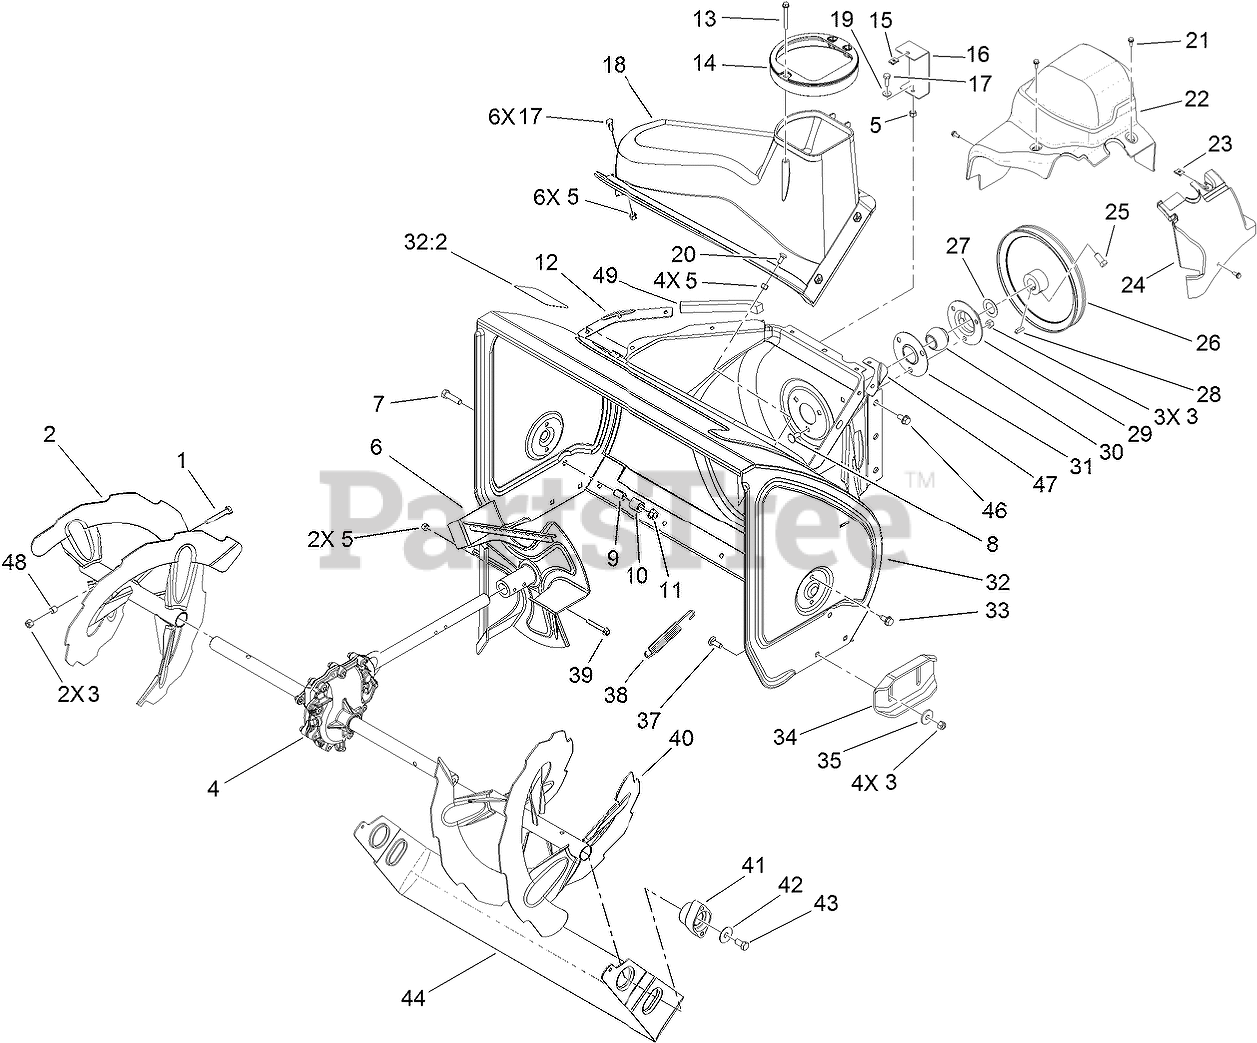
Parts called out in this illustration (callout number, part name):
1	SCREW-HH
2	RH AUGER ASM
3	NUT-LOCK, NI
4	28 INCH AUGER GEARCASE ASM
5	NUT-LOCK, NI
6	IMPELLER ASM
7	SCREW-HH
8	SCREW-CARR
9	SPACER-SCRAPER, STOP
10	CUSHION-SCRAPER, STOP
11	NUT-HF
12	SEAL-FLANGE, COVER
13	SCREW-PLASTITE
14	GUIDE-CHUTE
15	NUT-SPEED, U-TYPE
16	BRACKET-COVER, CLIP NUT
17	SCREW-HH
19	WASHER-FLAT
20	BOLT-CARR
21	SCREW-HWH
22	COVER-BELT
23	NUT-SPEED
24	COVER-EXTENSION, BELT
25	SCREW-SET, SQH
26	PULLEY-IMPELLER
27	WASHER-THRUST
28	KEY-WOODRUFF
29	FLANGE-CUP, BEARING
30	BEARING-BALL
31	FLANGE-CUP, BEARING
32	HOUSING-AUGER, 28 INCH
32:2	DECAL-DANGER, AUGER
33	SCREW-HWHTF
35	WASHER
37	SCREW-CARR
38	SPRING-SCRAPER
39	SCREW-HH
40	LH AUGER ASM
41	BEARING-AUGER
42	WASHER
43	SCREW-HH
44	SCRAPER-PIVOTING, 28 INCH
46	SCREW-HWHTF
48	SPACER
49	SEAL-HOUSING
